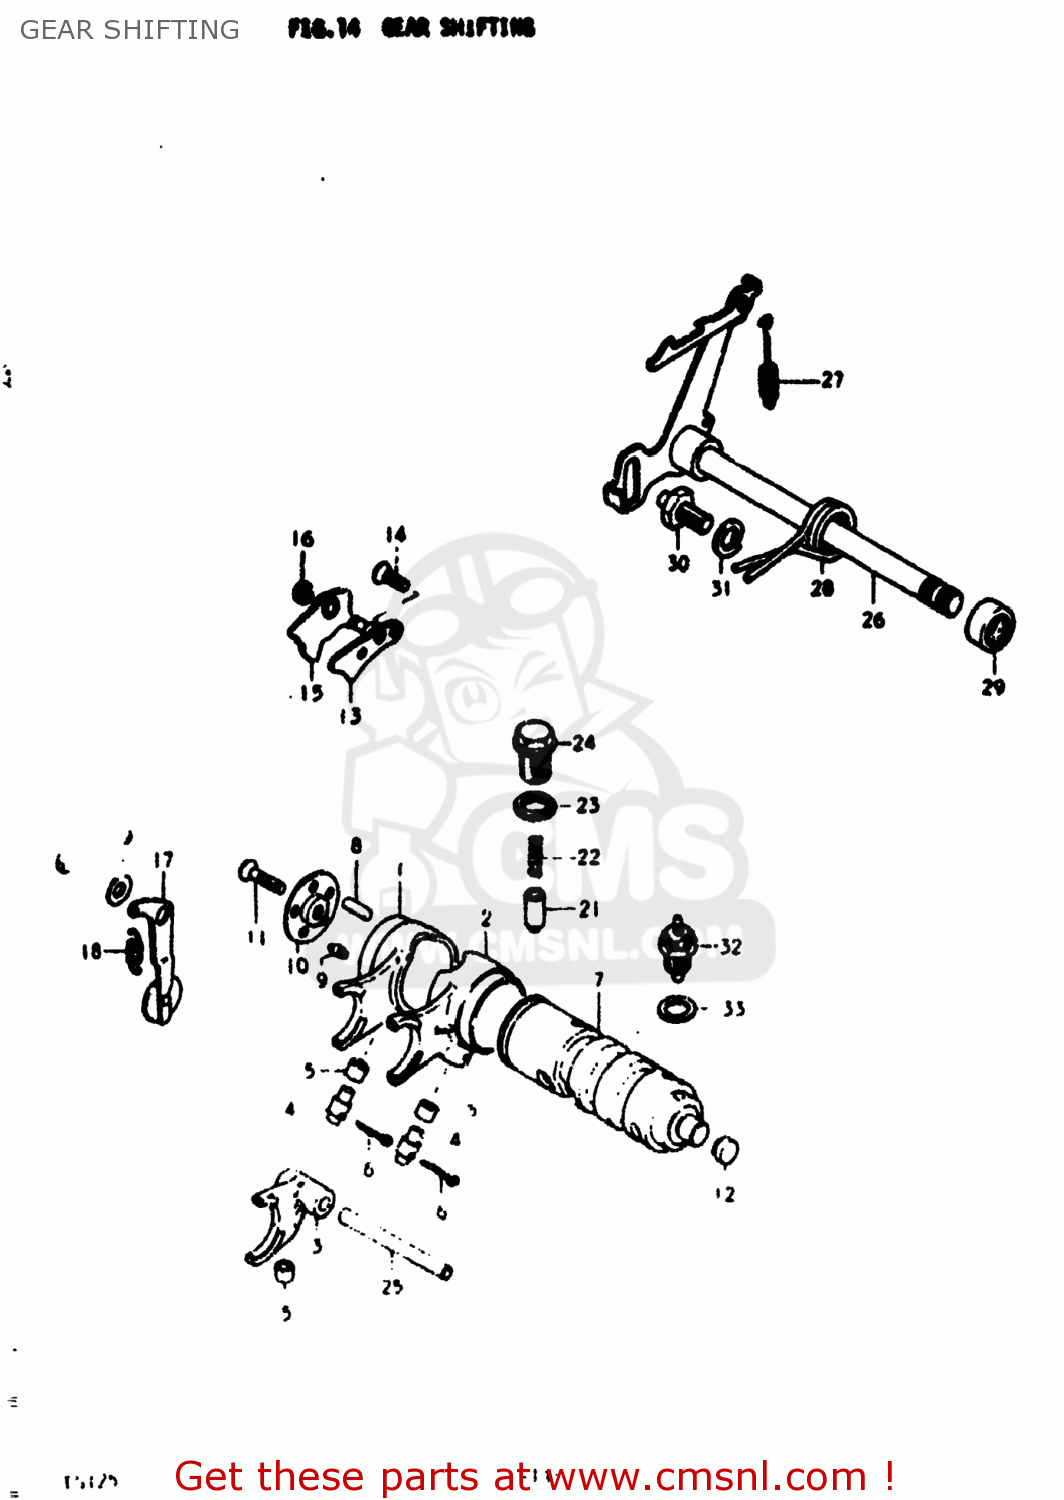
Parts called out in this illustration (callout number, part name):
1	FORK,GEAR SHIFT NO.1
2	FORK,GEAR SHIFT NO.2
3	FORK,GEAR SHIFT NO.3
4	PIN
5	SPACER
6	PIN 25X20
7	CAM,GEAR SHIFT
8	ROLLER(4X13.8)
9	PIN
10	RETAINER,GEAR SHIFT CAM DR PIN
11	SCREW
12	PLUG
13	GUIDE,GEAR SHIFT CAM
14	SCREW
15	PAWL,GEAR SHIFTING CAM
16	E RING
17	STOPPER,GEAR SHIFT CAM
18	SPRING
19	WASHER(6.5X16X2.3)
20	BOLT(6X16.1)
21	STOPPER,GEAR SHIFTING
22	SPRING
23	GASKET(14X19.2X2) (NAS)
24	BOLT,GEAR SHAFT CAM STOPPER
25	SHAFT,GEAR SHIFT FORK
26	SHAFT,GEAR SHIFT
27	SPRING
28	SPRING
29	OIL SEAL
30	STOPPER,GEAR SHIFT ARM
31	LOCK WASHER
32	SWITCH ASSEMBLY,NEUTRAL INDICATOR
33	GASKET(12.5X20X1) (NAS)
